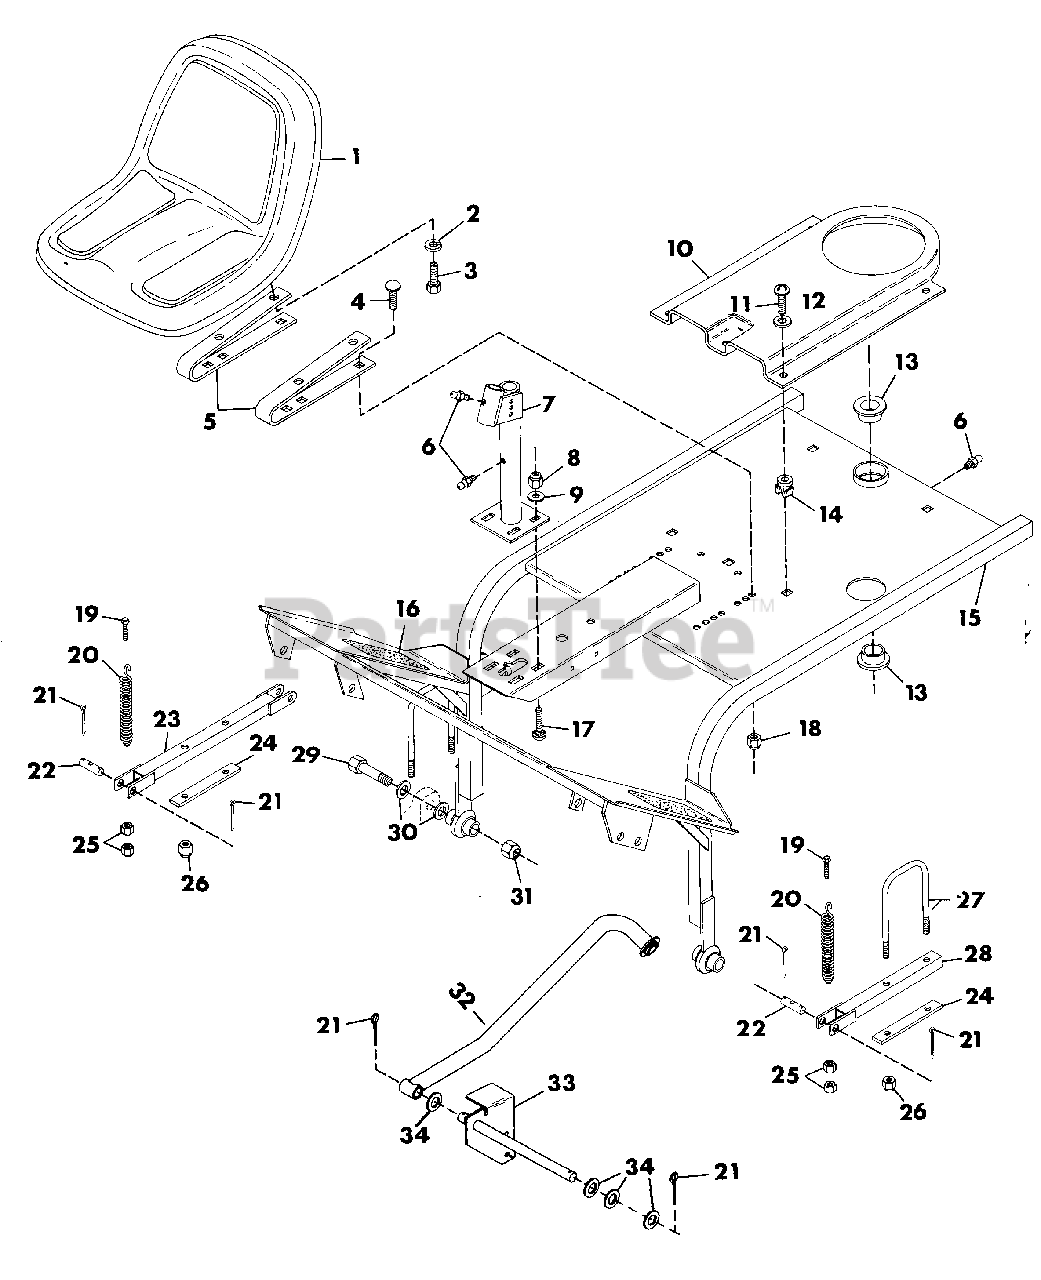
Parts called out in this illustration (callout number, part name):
1	SEAT, HIGH BACK
2	WASHER, LOCK 5/16
3	BOLT, HEX 5/16-18X.75
4	BOLT, CARRIAGE 5/16-18X1.00
5	SPRING, SEAT
6	FITTING, LUBE 1/4-28
7	TUBE, STEERING
8	NUT, LOCK 3/8-16
9	WASHER, FLAT .406X.812X.065
10	COVER, CHAIN
11	SCREW, MACHINE 1/4-20X.625 RD HD
12	WASHER, FLAT .281X.625X.065
13	BEARING, FLANGED
14	GROMMET, PLASTIC
15	WELDMENT, FRAME OFC
16	COVER, LARGE FOOTBOARD
17	BOLT, 3/8-16X1.00 RD HD SQ NK
18	NUT, LOCK 5/16-18
19	BOLT, HEX SPECIAL 3/8-16X3.00
20	SPRING, TRIP
21	PIN, COTTER .125X1.25
22	PIN, PIVOT
23	WELDMENT, LIFT ARM
24	PLATE, AXLE
25	NUT, HEX 3/8-16
26	NUT, LOCK 5/8-18
27	BOLT, U
28	ARM, SPRING PIVOT
29	BOLT, HEX 3/4-10X3.75
30	WASHER, FLAT .813X2.0X.148
31	NUT, LOCK 3/4-10
32	WELDMENT, LIFT LEVER
33	WELDMENT, LIFT BRACKET
34	WASHER, FLAT .656X1.250X.100
